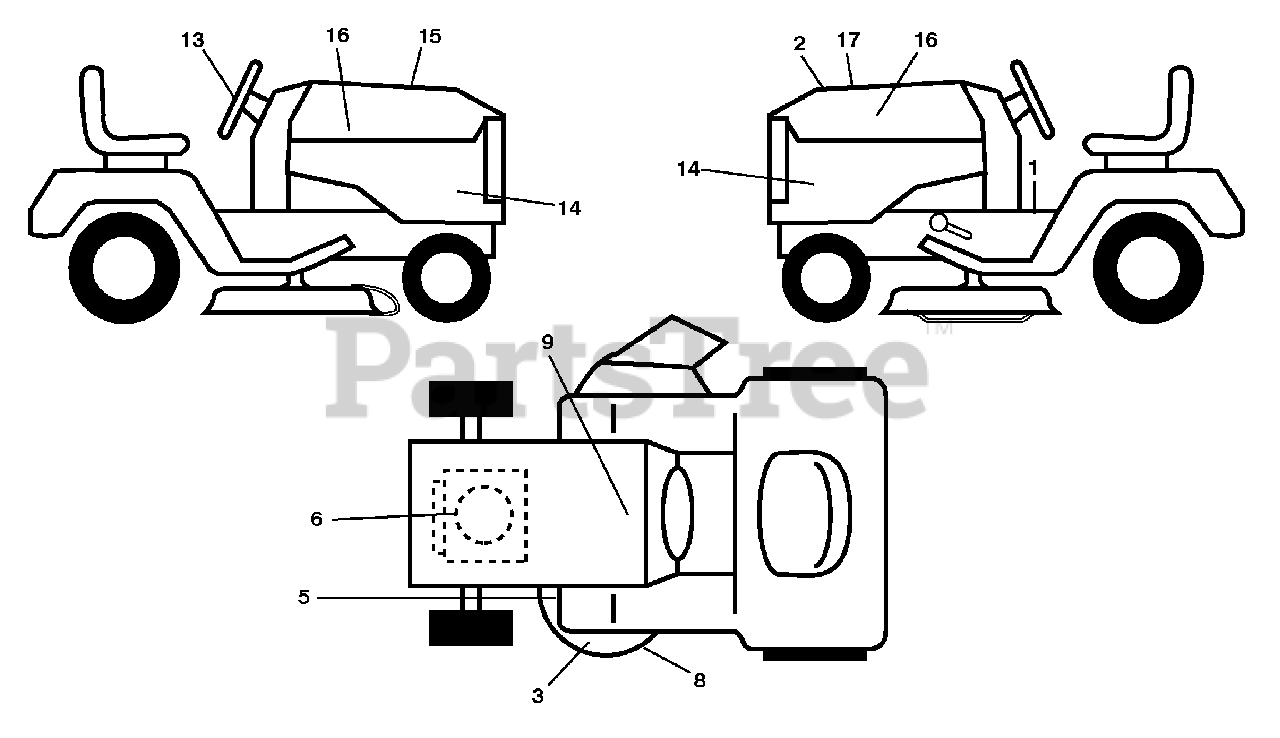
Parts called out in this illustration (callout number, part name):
1	Decal, Operator's
2	Decal, Hood Insert
3	Decal, Warning
5	Decal, Caution
6	Decal, Eng. HP
8	Decal, Mower Sch.
9	Decal, Battery Dnge/Poi
13	Decal, Steering Whl
14	Decal, Panel Side
15	Decal, Cust. Resp.
16	Decal, Hood Logo
17	Decal, Replacement
17	Decal, Bypass
